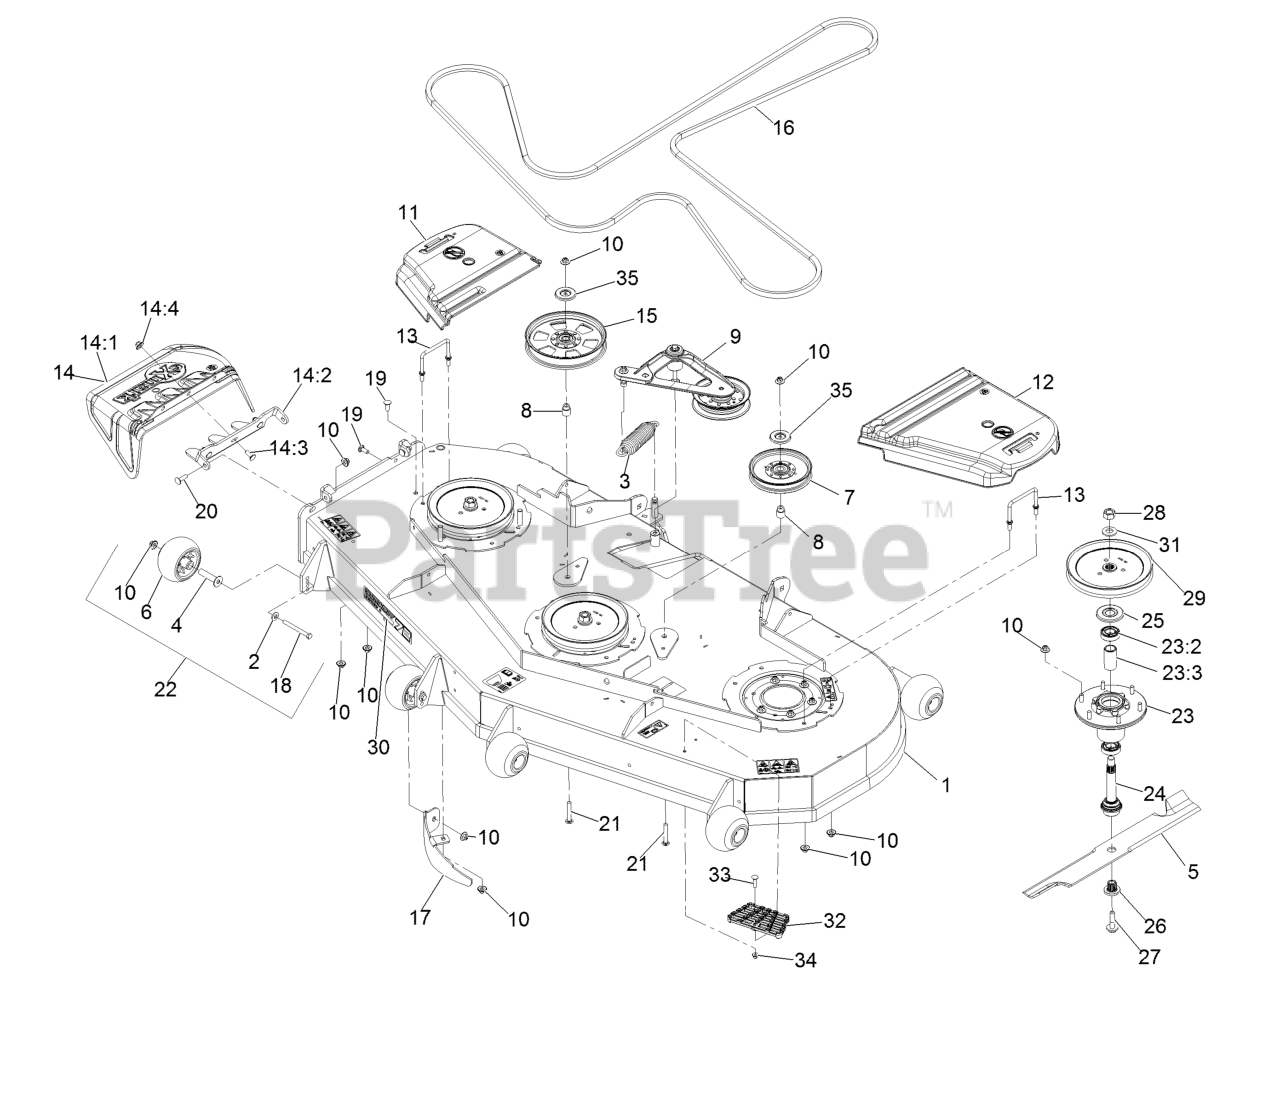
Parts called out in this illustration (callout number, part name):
1	ASM,Deck W/Decals 724
2	Washer-Spring Disc 3/8
3	Spring-Extension
4	Axle, Roller
5	Blade, Solid (72")
5	Blade, Low Lift (72")
5	Blade, Mulching (72")
5	Blade, Notched (72")
5	Blade-Extreme 2, 24.50"
6	Roller-Anti-Scalp
7	Idler-Pulley
8	Bushing, Idler
9	Deck Idler ASM
10	Nut-Nyloc 3/8-16 Flg
11	Cover-Belt, RH
12	Cover-Belt, LH
13	Wireform-Cover
14	ASM,Discharge Chute
14:1	Chute, Discharge
14:2	Bracket,Discharge Chute
14:3	Bolt-Carriage 3/8-16 X 1
14:4	Nut-Nyloc 3/8-16 Flg
15	Pulley-Idler, Flat
16	Belt-V
17	Baffle-Dogleg, Lz72
18	Screw-HH 3/8-16 X 3 3/4 GR 8
19	Bolt-Carriage 3/8-16 X 1
20	Bolt-Carriage 3/8-16 X 1 1/4
21	Bolt-Carriage 3/8-16 X 2 1/2
22	Kit, Anti-Scalp Roller
23	ASM-Cutter Hsg With Bearings
23:2	Bearing-Ball
23:3	Spacer-Bearing
24	ASM-Spindle And Seal
25	Guard,Bearing Top .989
26	Bushing, Splined
27	Screw-Sems 1/2-20 X 2.19
28	Nut-Hex
29	Sheave,Blade Drive 8.74
30	Decal, 724
31	Washer-Spring Disc 3/4
32	Step-Deck
33	Screw-CARR
34	Nut-HF, NI
35	Shield-Dust
